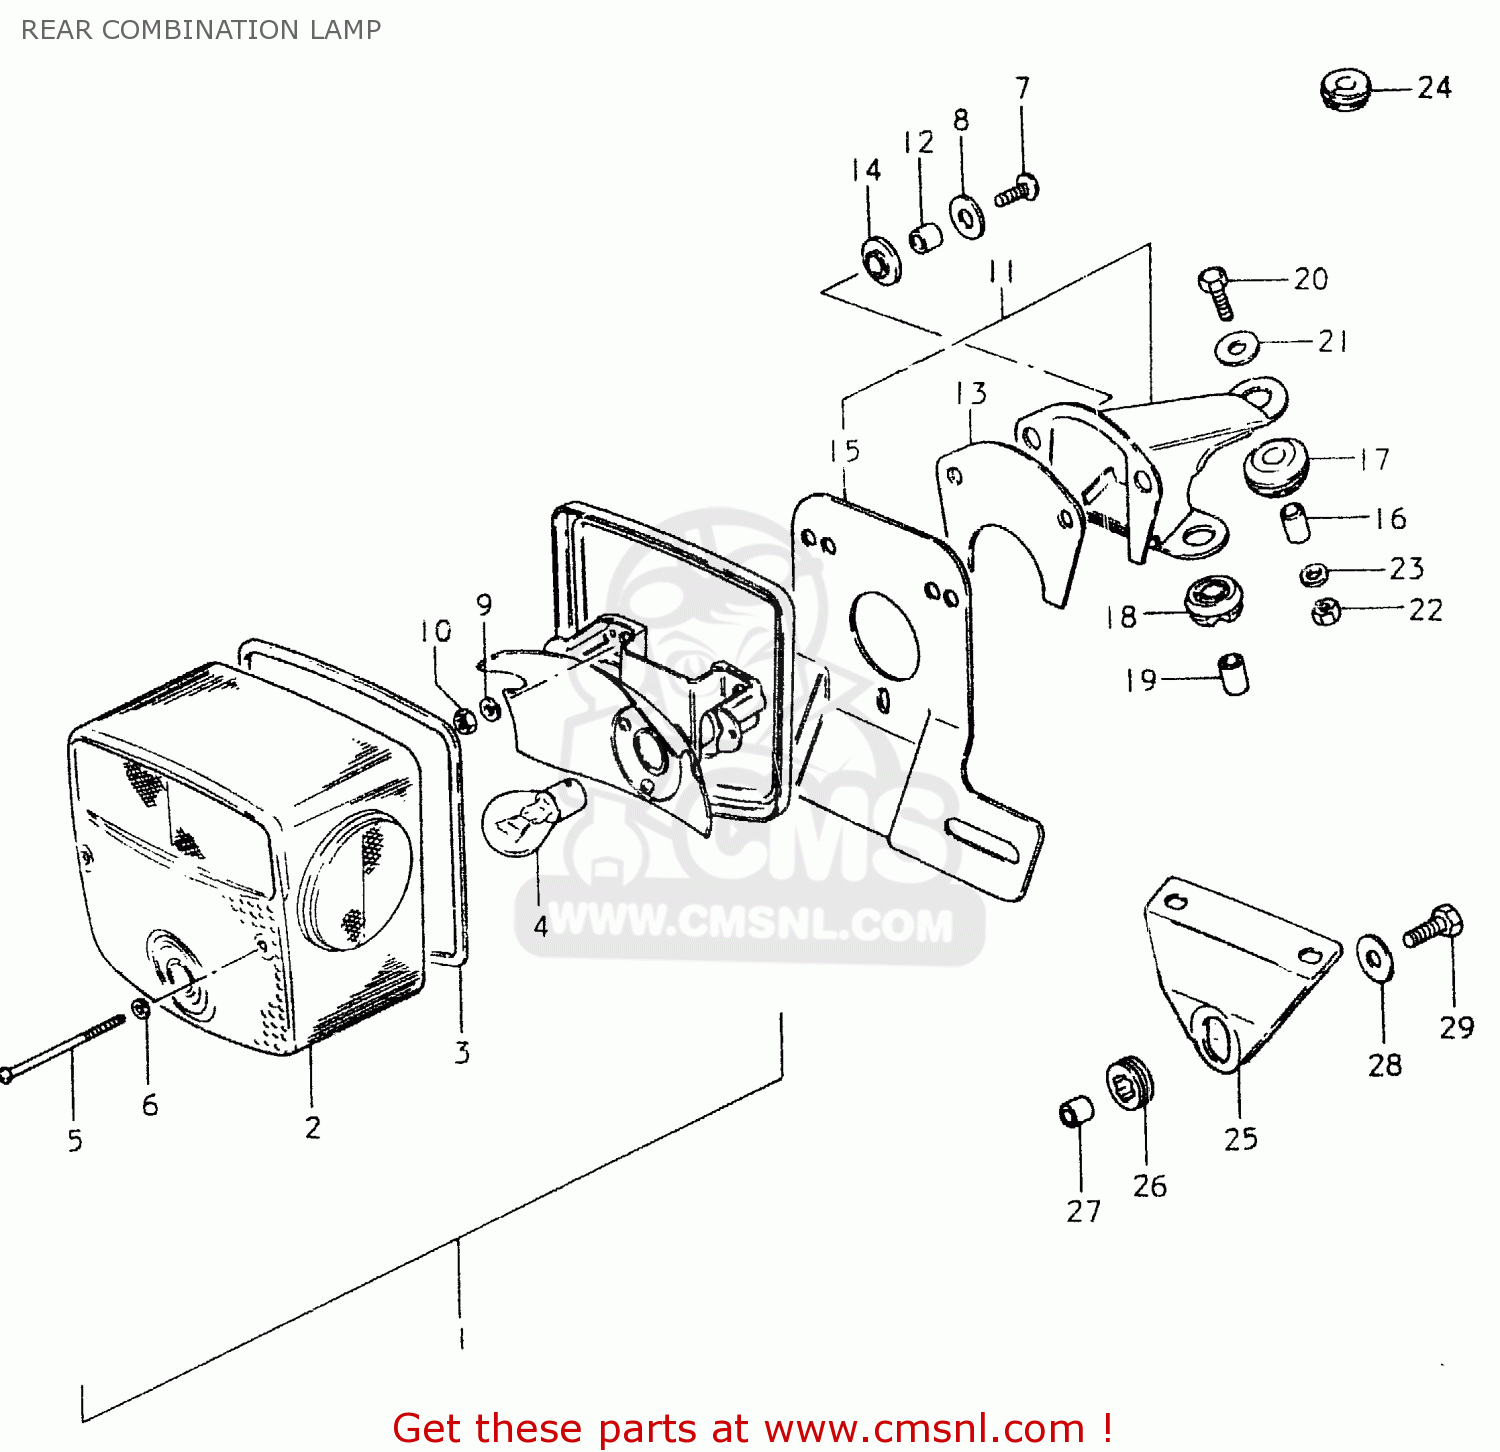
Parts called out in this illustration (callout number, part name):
1	LAMP UNIT, TAIL
2	LENS
3	GASKET (NAS)
4	BULB(6V32/3CP,STANLEY)
5	SCREW (4X55)
6	GASKET (NAS)
7	TAPPING SCREW
8	WASHER,REAR COMBINATION LAMP
9	NUT
10	LOCK WASHER
11	BRACKET SET
12	SPACER
13	CUSHION
14	CUSHION,REAR COMBINATION LAMP
15	PLATE, LICENCE
16	SPACER
17	CUSHION,REAR COMBINATION LAMP
18	CUSHION,REAR COMBINATION LAMP
19	SPACER
20	BOLT
21	WASHER (6.5X20X1.2)
22	NUT
23	WASHER 6MM
24	GROMMET
25	REINFORCEMENT
26	CUSHION
27	SPACER (6.1X9X9)
28	WASHER (6.5X20X1.2)
29	BOLT, UPPER
